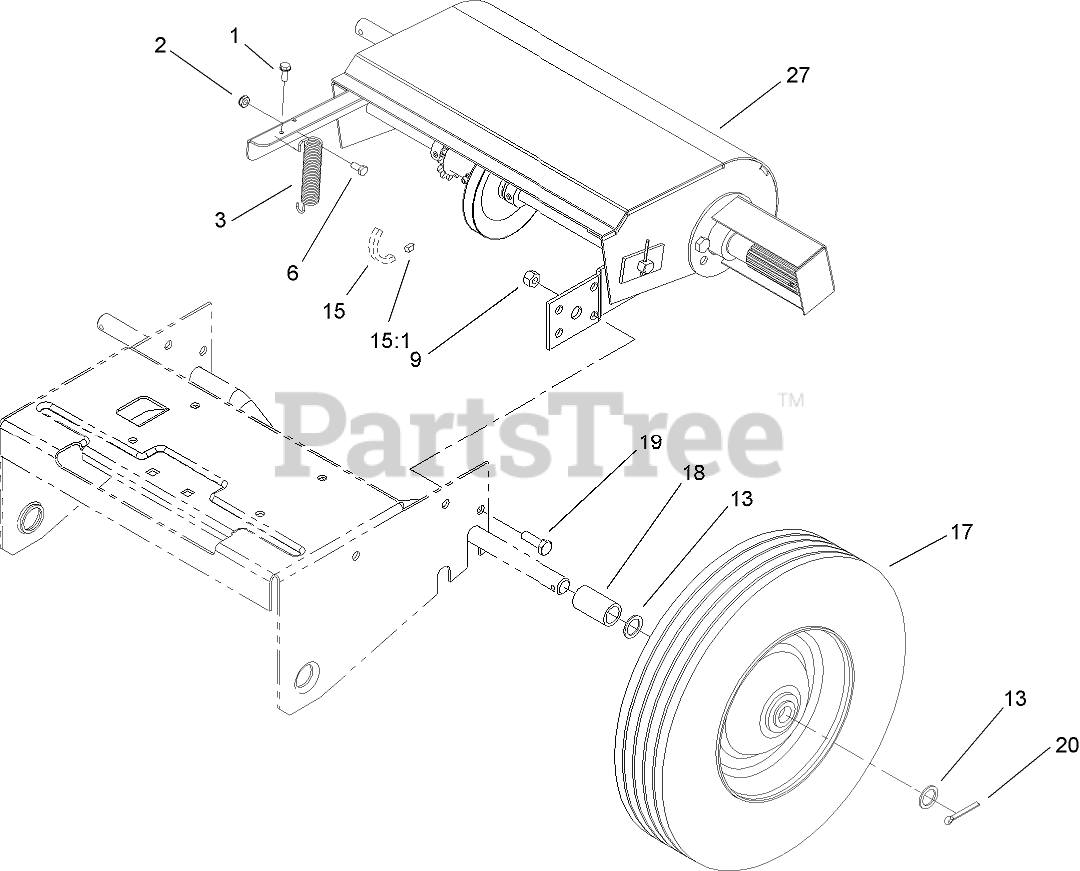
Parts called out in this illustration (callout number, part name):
1	SCREW-HH
2	NUT-LOCK, NI
3	SPRING-TRACTION
6	SCREW-HH
9	NUT-LOCK, NI
13	WASHER
15	CHAIN-ROLLER, REEL DRIVE
15:1	LINK-CONNECTING, NO. 35
17	WHEEL
18	SPACER-AXLE
19	SCREW-HH
20	PIN-COTTER
27	Traction ASM
